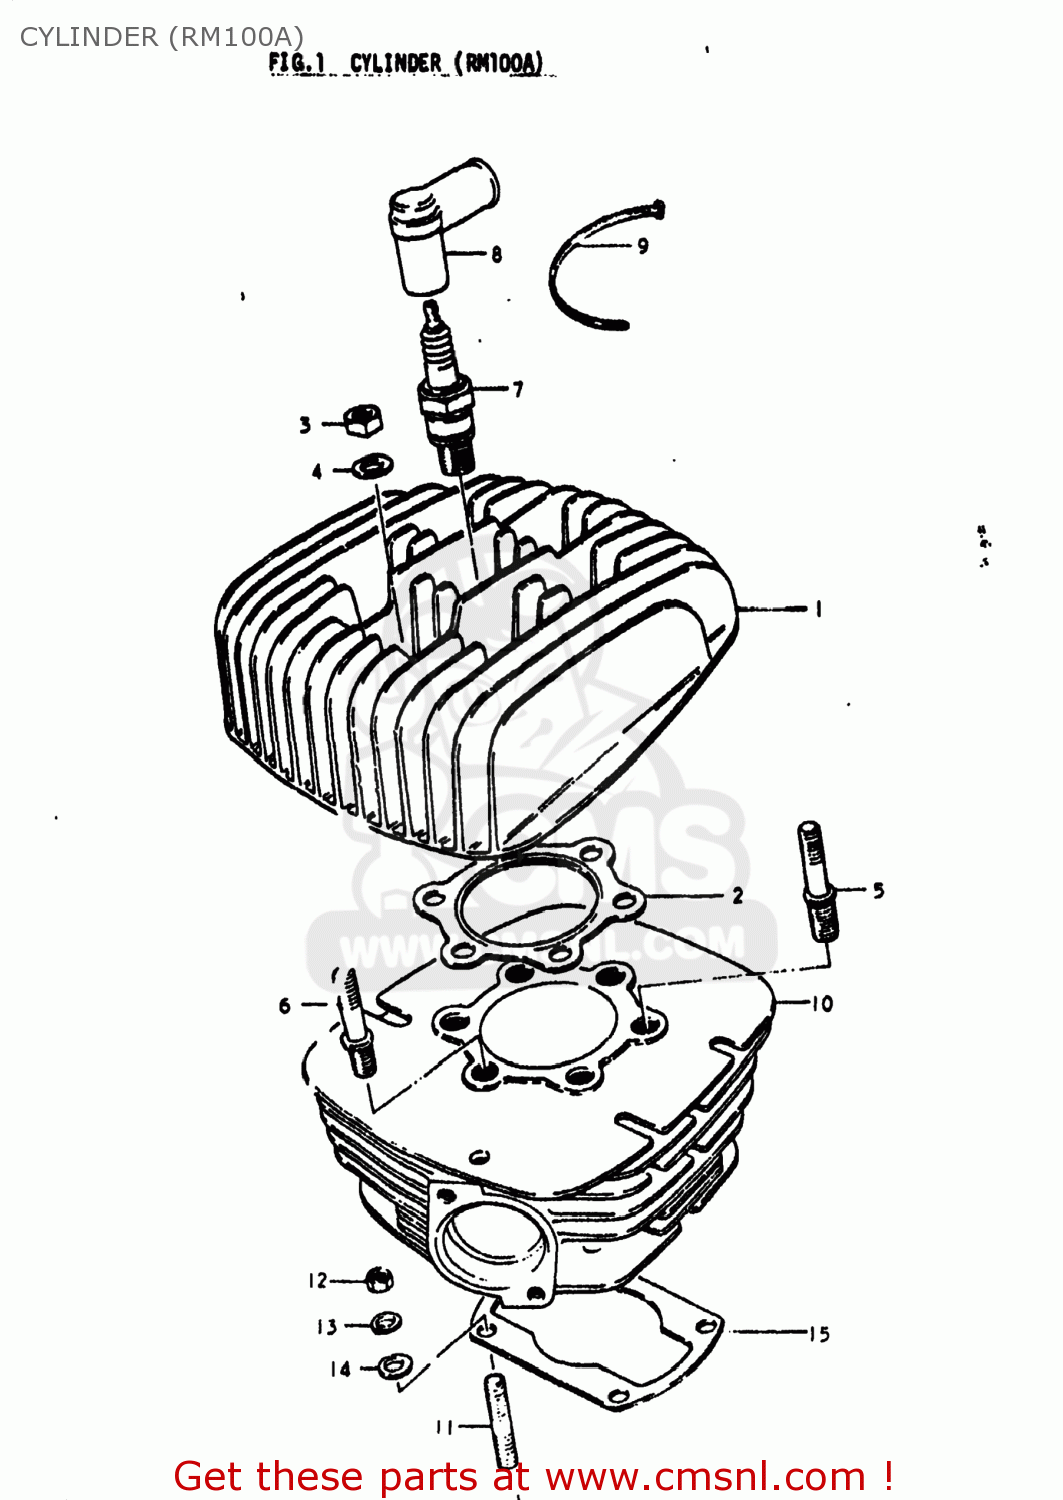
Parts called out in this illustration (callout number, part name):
1	HEAD,CYLINDER
2	GASKET,CYLINDER HEAD (MCA)
3	NUT (8MM)
4	WASHER
5	BOLT,STUD
6	STUD
7	SPARK PLUG
8	CAP,SPARK PLUG
9	CLAMP
10	CYLINDER
11	STUD 8X25
12	NUT
13	LOCK WASHER
14	WASHER
15	GASKET,CYLINDER (MCA)
